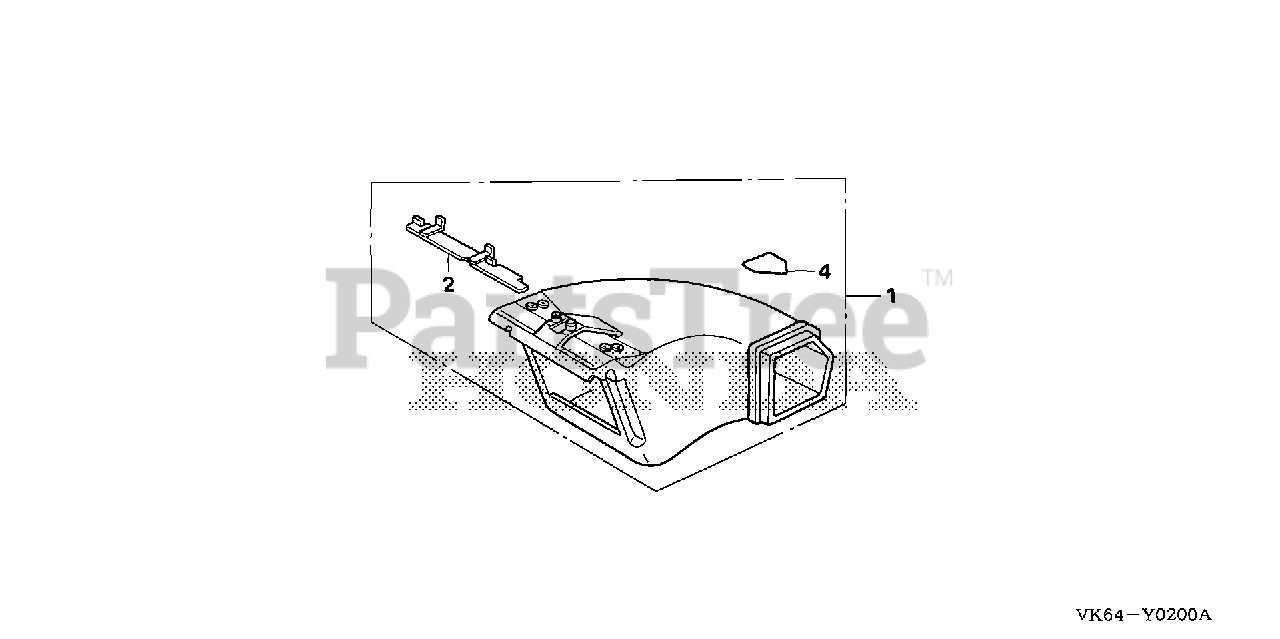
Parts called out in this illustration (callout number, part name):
1	CHUTE KIT, SIDE DISCHARGE
2	BRACKET, MOUNTING
4	CAUTION C, HOUSING
